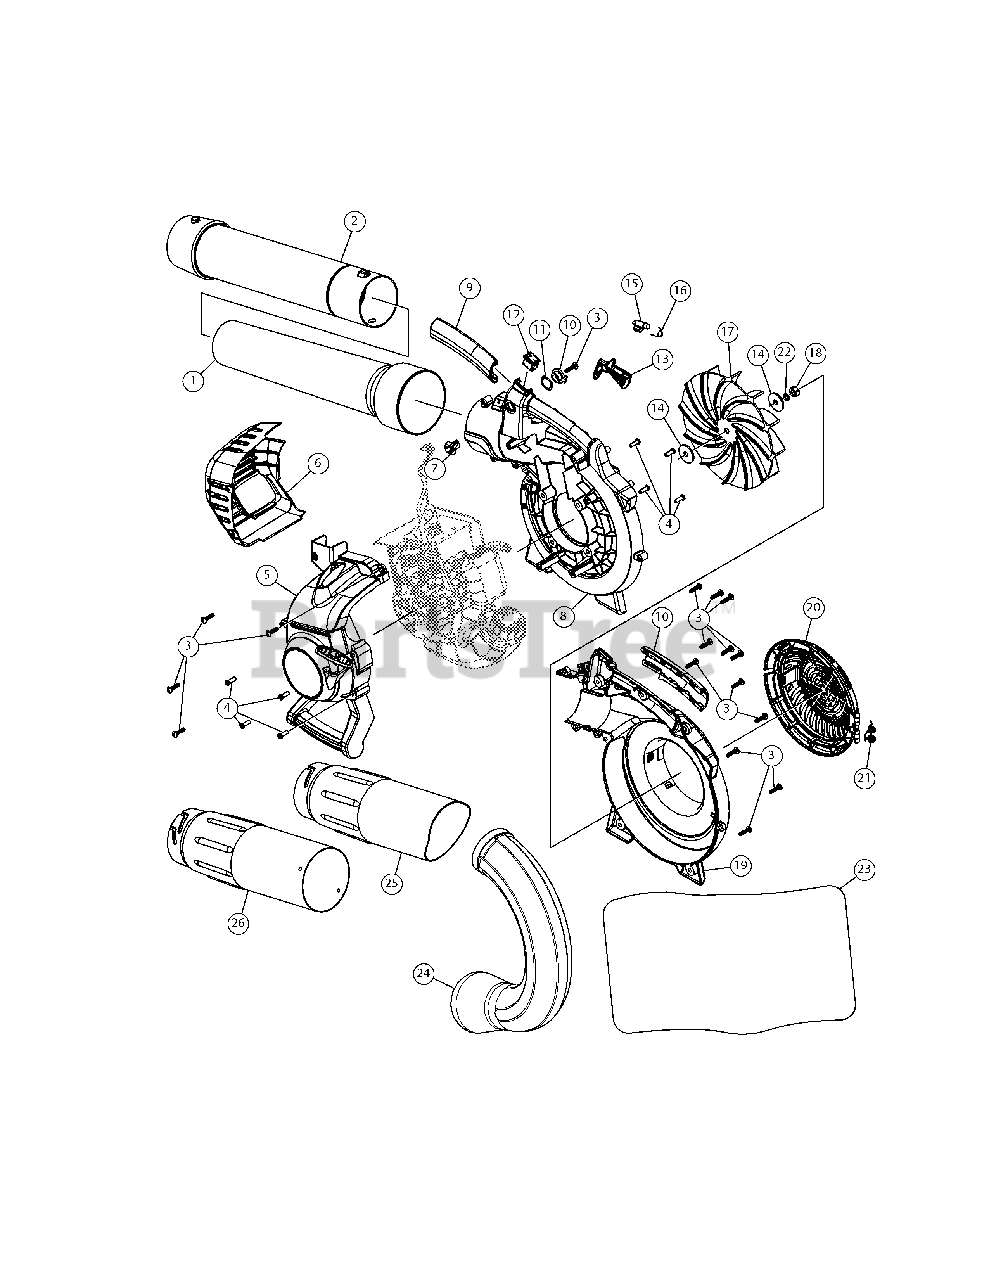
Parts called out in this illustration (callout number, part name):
1	Lower Tube
2	Upper Tube
4	Screw
5	Engine Cover Assembly (Incl. 3 & 4)
6	Muffler Cover Assembly (Incl. 3)
7	Outer Trigger Lock
8	Impeller Housing
9	Handle Grips
10	Inner Trigger Lock
11	Wavey Washer
13	Throttle Trigger
15	Latch Tube
16	Latch Spring
18	Nut
19	Impeller Housing
20	Intake Cover
22	Lock Washer
25	Lower Vac Tube
26	Upper Vac Tube
